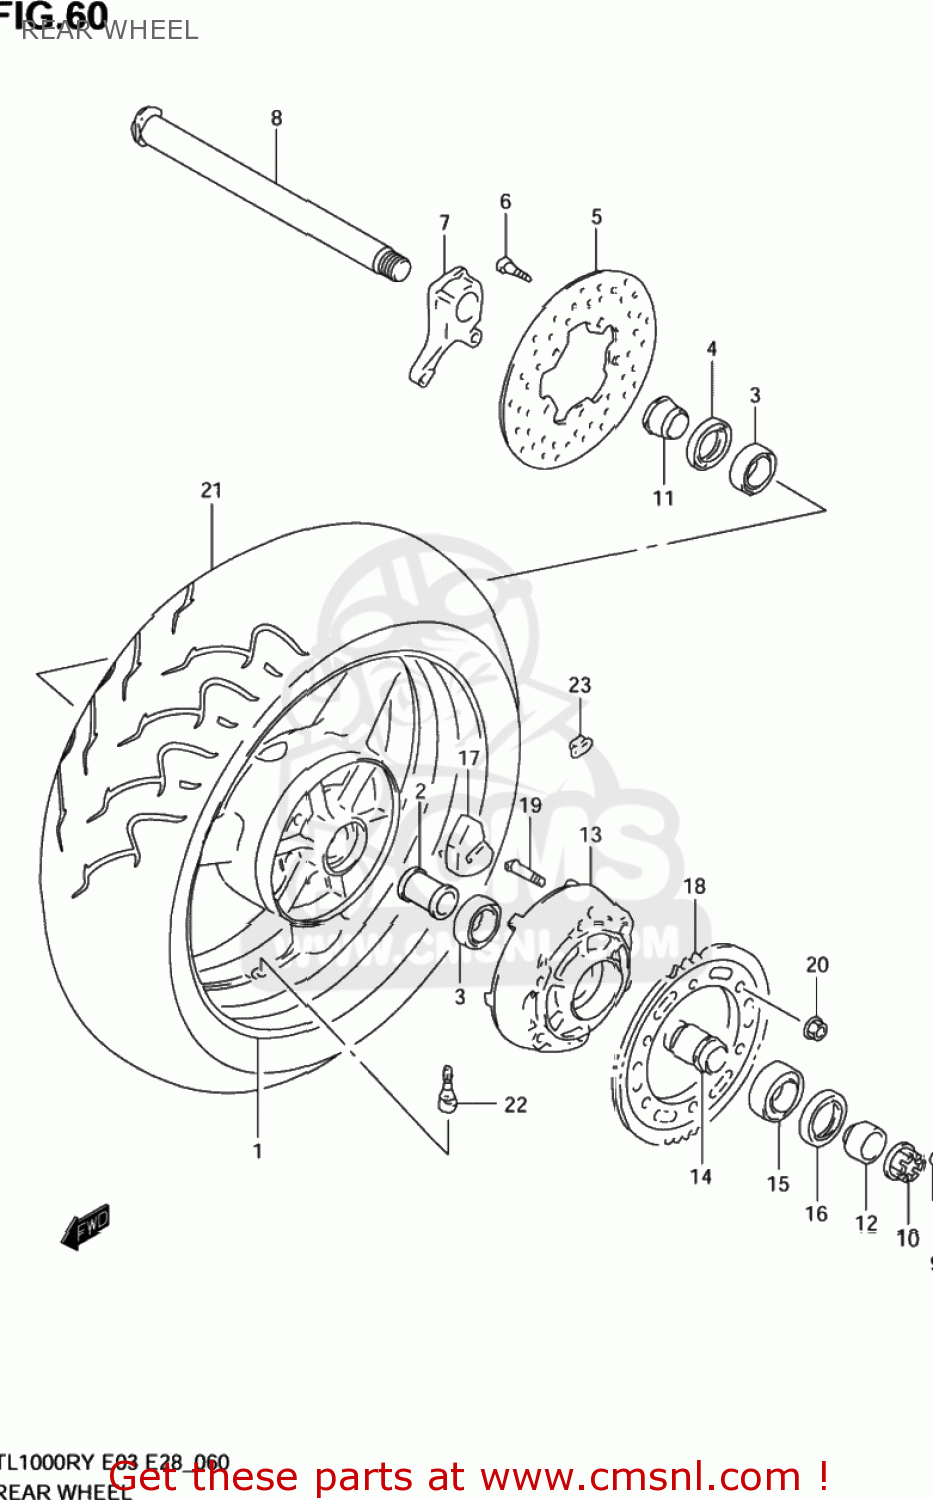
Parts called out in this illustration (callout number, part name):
1	WHEEL,REAR,17X
2	SPACER,RR HUB BEARING
3	BEARING(32X58X13)
4	SEAL,OIL(38X58X7)
5	DISC,RR BRAKE
6	BOLT 8X33
7	BRACKET,RR CALIPER
8	AXLE,RR
9	PIN, COTTER
10	NUT
11	SPACER,RR AXLE,R
12	SPACER,RR AXLE,L
13	DRUM,RR SPROCKET
14	RETAINER,RR SPROCKET DRUM
15	BEARING
16	SEAL,OIL(39X65X7)
17	ABSORBER,RR HUB SHOCK
18	SPROCKET,RR(NT:39-530)
19	BOLT
20	NUT
21	TIRE 190/50 ZR17 (73W)
22	VALVE ASSY,WHEEL RIM(TR412)
23	BALANCER,WHEEL (10G)
